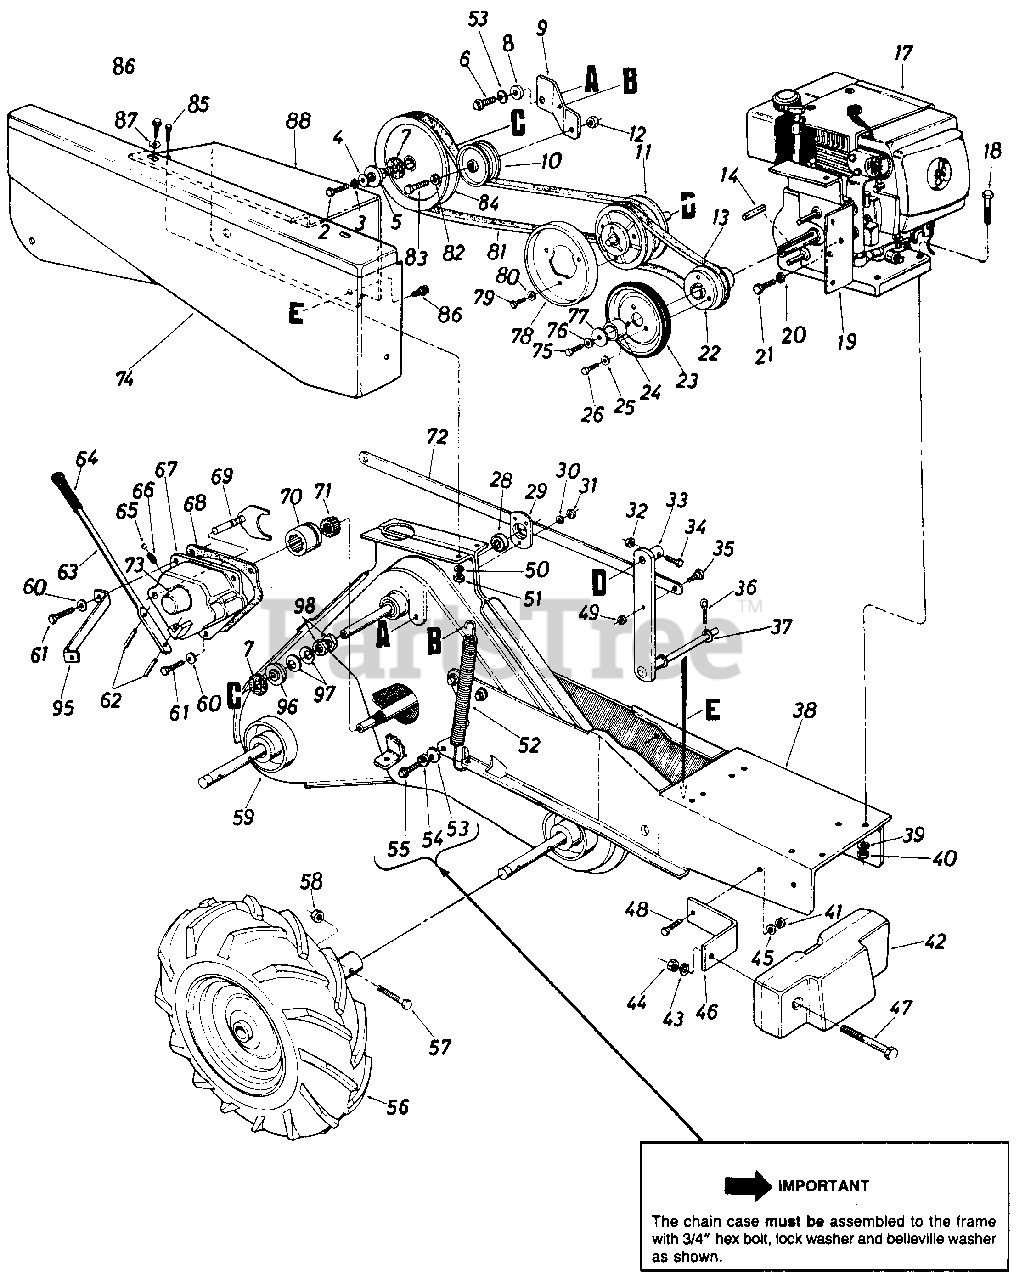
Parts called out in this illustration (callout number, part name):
2	Hex L-Bolt 5/16-24 x 1.5" Lg.
3	L-Wash. 51/6" I.D.*
4	Fl-Wash. 5/16" I.D. x 1.125" O.D.
5	Friction Disc Ass'y.
6	Hex Bolt 3/8-24 x 1.25" Lg.
7	Friction Pad
8	Shoulder Spacer
9	Idler Bracket
10	Fl-ldler 2.75" Dia.
11	Variable Speed Ass'y.
12	Hex Ins. L-Nut 3/8-16 Thd.
13	"V"-Belt 5/8" x 27.0" Lg.
14	Sq Key 1/4" x 2.00" Lg.*
17	Engine
18	Hex Bolt 5/16-18 x 1.75" Lg.
19	Belt Cover Support Ass'y.
20	Internal L-Wash. 1/2" I.D.
21	Hex Bolt 1/2-20 x .75" Lg.
22	Engine Pulley Ass'y.
23	Friction Wheel Ass'y.
25	L-Wash. 5116" I.D.*
26	Hex Bolt 5/16-18 x .50" Lg.*
28	Ball Bearing
29	Bearing Housing 1-3/8" O.D.
30	L-Wash. 1/4" I.D.*
31	Hex Nut 1/4-28 Thd.*
32	Hex Ins. L-Nut 1/4-20 Thd.
33	Variable Speed Brkt. Ass'y.
34	Hex Bolt 1/4-20 x 1.25" Lg.*
35	Shld. Bolt 1/2" Dia. x .25" Lg.
36	Cotter Pin 1/8" Dia. x 1.01' Lg.
37	Fl-Wash. .686" I.D. x 1.25" O.D.
38	Frame Ass'y.
39	L-Wash. 5/16" I.D.*
40	Hex Nut 5/16-18 Thd.*
41	Hex Cent. L-Nut 3/8-24 Thd.
43	Fl-Wash. .50" I.D. x 1.0" O.D.
44	Hex Nut 1/2-13 Thd.*
45	L-Wash. 3/8" I.D.*
46	Weight Mtg. Brkt.
47	Hex Bolt 1/2-13 x 4.50" Lg.*
48	Hex Bolt 3/8-24 x 1.00" Lg.*
49	Hex Ins. L-Nut 3/8-16 Thd.
50	L-Wash. 1/4" I.D.*
51	Hex Cent. L-Nut 1/4-28 Thd.
52	Spring Idler Bracket
53	Belleville Wash. 318" I.D.
54	L-Wash. 3/8" I.D.*
55	Hex Self-Tap Scr. 3/8-16 x .75" Lg.
56	Wheel Ass'y. Comp.-R.H.
57	Hex Bolt 3/8-24 x 1.25" Lg.
58	Hex Ins. L-Nut 3/8-24 Thd.
59	Chain Case Ass'y. Comp.
60	L-Wash. 5/16" I.D.
61	Hex Tap Tite Scr. 5/16-18 x .75" Lg.
62	Headed Spiral Pin 3/16 x 13/16" Lg.
63	Engagement Lever
65	Ball Detent .250" Dia.
66	Compression Spring
67	Shift Housing-R.H.
68	Gasket-Shift Housing
69	Shift Yoke Ass'y.-R.H.
70	Clutch Dog
71	Clutch Dog Driver
72	Control Brkt.
73	Bearing (Incl. w/Ref. 76)
74	Shroud Belt Cover
75	Hex Bolt 7/16-20 x 2.25" Lg.
76	L-Wash. 7/16" I.D.
77	Fl-Wash. .44 I.D. x 1.38" O.D.
78	Friction Disc
79	Hex Bolt 1/4-28 x .50" Lg.
80	L-Wash. 1/4" I.D.
81	"V"-Belt 5/8" x 51 " Lg .
82	L-Wash. 3/8" I.D.
83	Hex Bolt 3/8" x 1.50" Lg.
84	Input Pulley-Chain Case
85	Hex Bolt 1/4-28 x .62" Lg.
86	Hex Wash. Hd. Self-Tap Scr.
87	Fl-Wash. 1/4" I.D.
88	Belt Cover Shroud
96	Floating Disc
97	Spring Bell-Wash.
98	Hex Jam Nut 1.0-14
